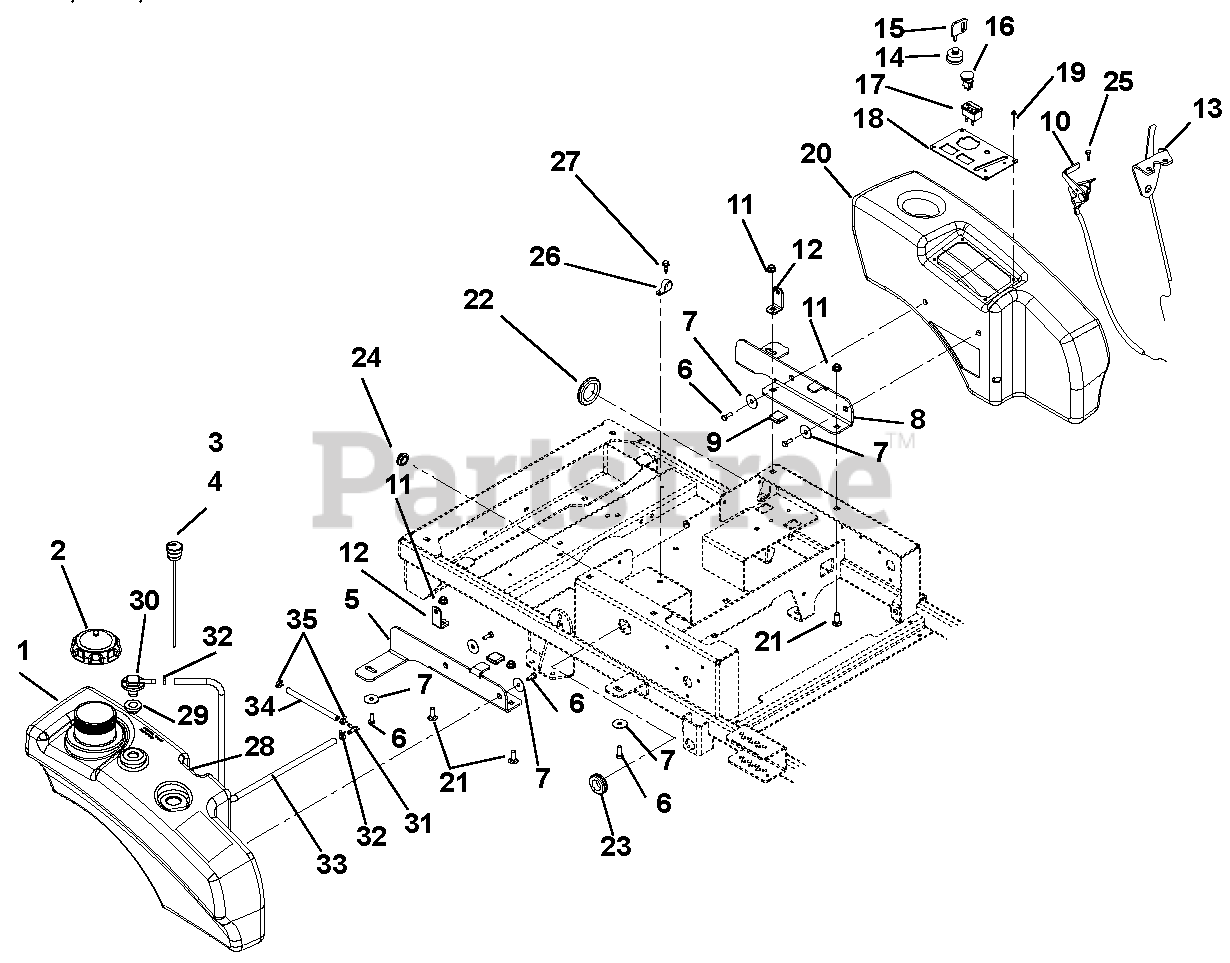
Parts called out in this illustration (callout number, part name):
1	Tank, XL (101 - 2499)
2	Fuel Cap (101 - 2499)
3	Gauge, Remote Fuel 10.0"
4	Grommet, Fuel Gage
5	Bracket, Right Hand Rear Tank Mount
6	Bolt, Serrated Hex Flange Washer Head .312-18 x .50
7	Washer, Flat Steel .347 x 1.254 x .048
8	Bracket, Left Hand Rear Tank Mount
9	Grip, Rubber
10	Cable, Throttle
11	Nut, .38-16 Nyloc Flange
12	Bracket, Hood Pivot
13	Cable, Choke
14	Key Switch
15	Key, w/cap
16	Switch, Clutch
17	Hour Meter, Digital
18	Panel, Control
19	Rivet, Plastic .195 Diameter
20	Fender, XL
21	Bolt, Round Head Square Neck .38-16 x 1.00 Grade 5
22	Grommet, 2.00"
23	Grommet .125 x 1.000 ID
24	Grommet, Rubber 5/8 ID/1.13 OD
25	Screw, Tapping 10-24 x .50 Hex Washer Head Thread
26	Clamp, Cushioned Steel
27	Screw, Tap Hex Washer Head .38-16 x .5
28	Tube, Fuel Pick-up (XL)
29	Grommet, Remote Vent, Nitrile (2500 - up)
30	Vent, Roll-over (.25" ID hose) (2500 - up)
31	Fitting, 3/16 x 1/4 90 Degree VAC (2500 - up)
32	Clamp, Fuel Line (2500 - up)
33	Hose, Low-Perm Bulk Gas (2500 - up)
34	Hose, .188 Low-Perm Bulk Gas (2500 - up)
35	Clamp, Hose, Spring .188 (2500 - up)
